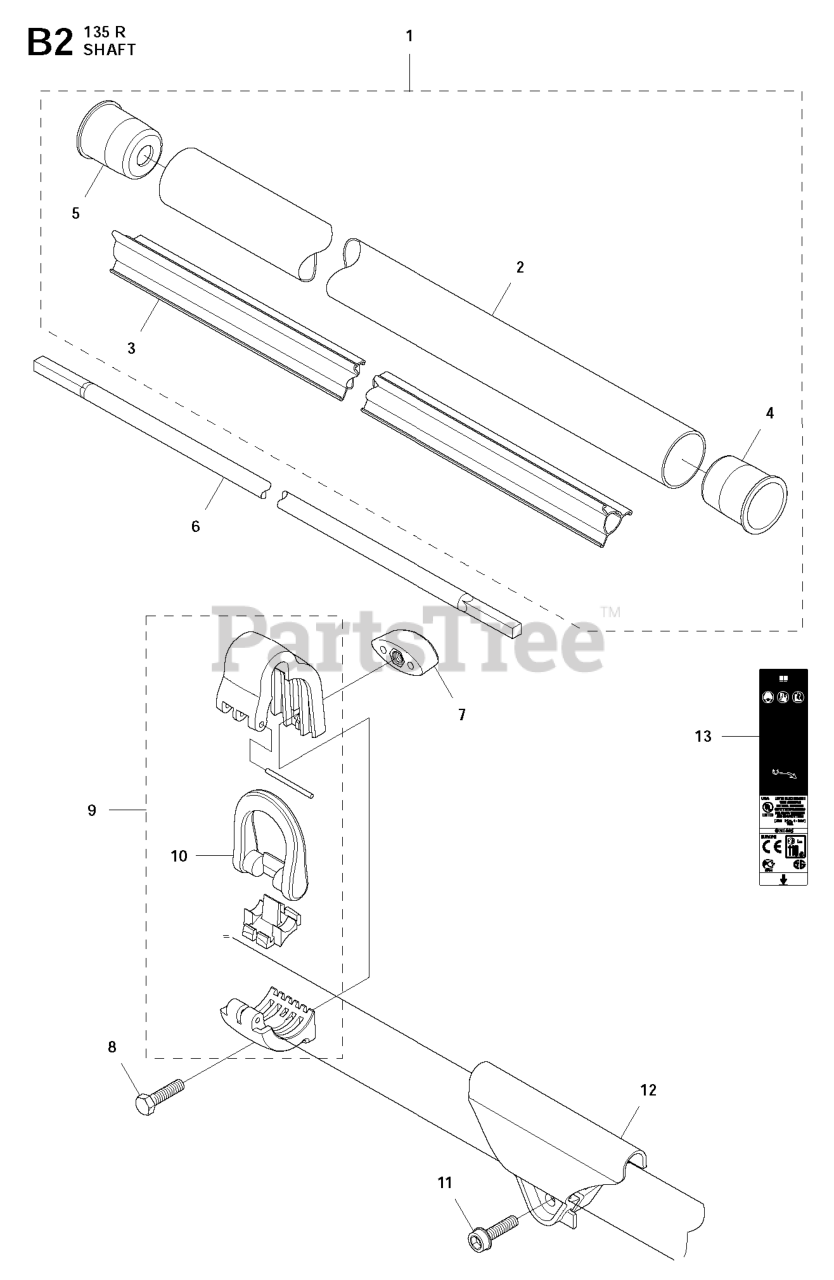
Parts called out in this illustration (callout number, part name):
2	TUBE
5	PLUG
8	SCREW M6S 5X20
12	CABLE HOLDER
13	LABEL WARNING TRIMMERS AND BRU
